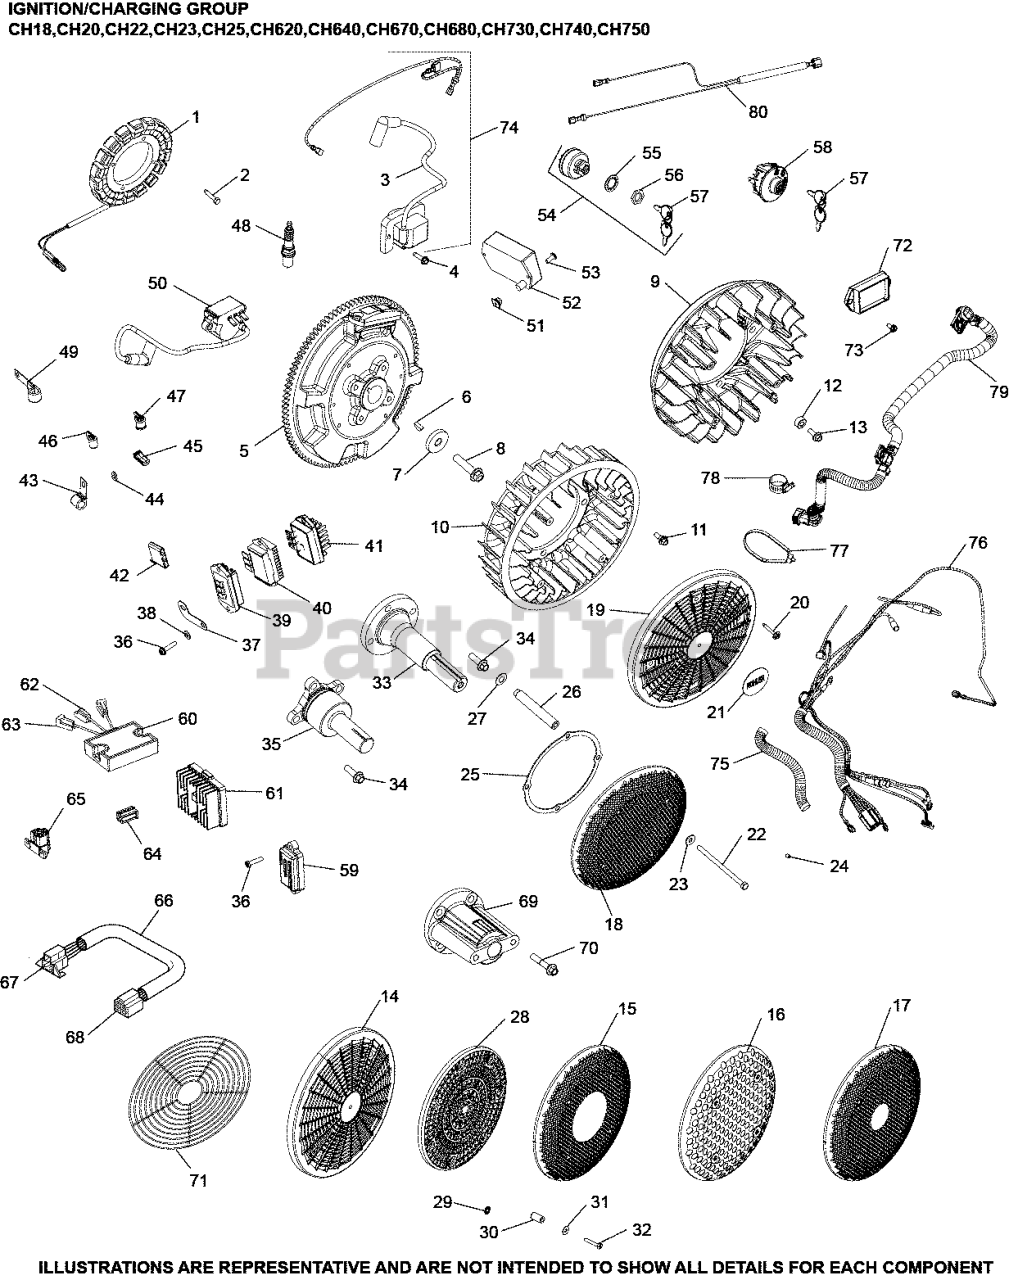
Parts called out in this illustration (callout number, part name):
1	STATOR KIT - USE 237878-S
2	SCREW, M5X0.8X25 - (#25086402S)
3	MODULE USE 24 584 36-S
5	FLYWHEEL, PAINTED-USE 24 025 56-S
6	KEY, 3/16" X 5/8"
7	WASHER, FLAT 13/32"
8	SCREW, FLG M10X1.5X45 - (#25086361S)
11	BOLT, SHOULDER
31	WASHER, FLAT 3/16"
33	SHAFT, FRONT DRIVE - DISCONTINUED
34	SCREW, FLG M8X1.25X25
36	SCREW, PHL HD #11-16X7/8"
42	CONNECTOR, BODY (KM)-USE 25 155 41-S
43	CLIP, CABLE
44	WASHER, FLAT 1/4" (O.D. 1/2")
48	PLUG, SPARK (STD)
51	NUT, PLASTIC
52	MODULE, SPEED ADVANCE-DISCONTINUED SEE PB265
53	SCREW, PHL HD #11-16X1/2"
1245403-S	TIE, CABLE
